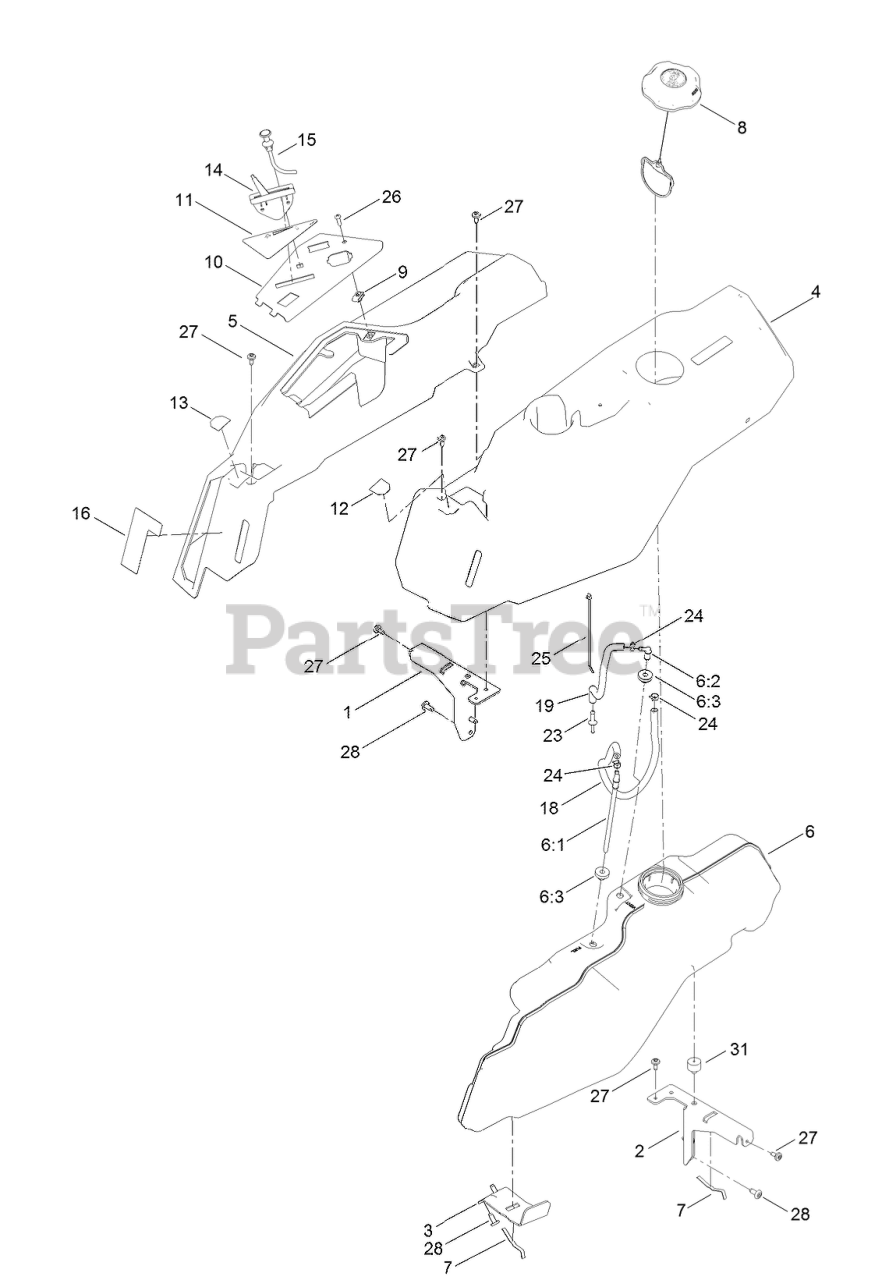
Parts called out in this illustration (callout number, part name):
1	SUPPORT-POD, RH
2	SUPPORT-POD, LH
3	SUPPORT-TANK, FUEL
4	POD-LH
5	POD-RH
6	FUEL TANK ASM
6:1	CONNECTOR-ELBOW, 90 DEG
6:2	FITTING-PLASTIC
6:3	BUSHING
7	SPRING
8	CAP-FUEL, RATCHETING
10	PANEL-CONTROL
11	DECAL-PANEL, CONTROL
12	DECAL-CONTROL LEVER, LH
13	DECAL-CONTROL LEVER, RH
14	CABLE-THROTTLE
15	CABLE-CHOKE
16	DECAL-SMART SPEED
18	HOSE-FUEL
19	HOSE-FUEL
23	ADAPTOR-ORIFICE
24	CLAMP-HOSE
25	TIE-CABLE
26	SCREW-PRH
27	SCREW-SHOULDER
31	BUMPER-GROMMET
